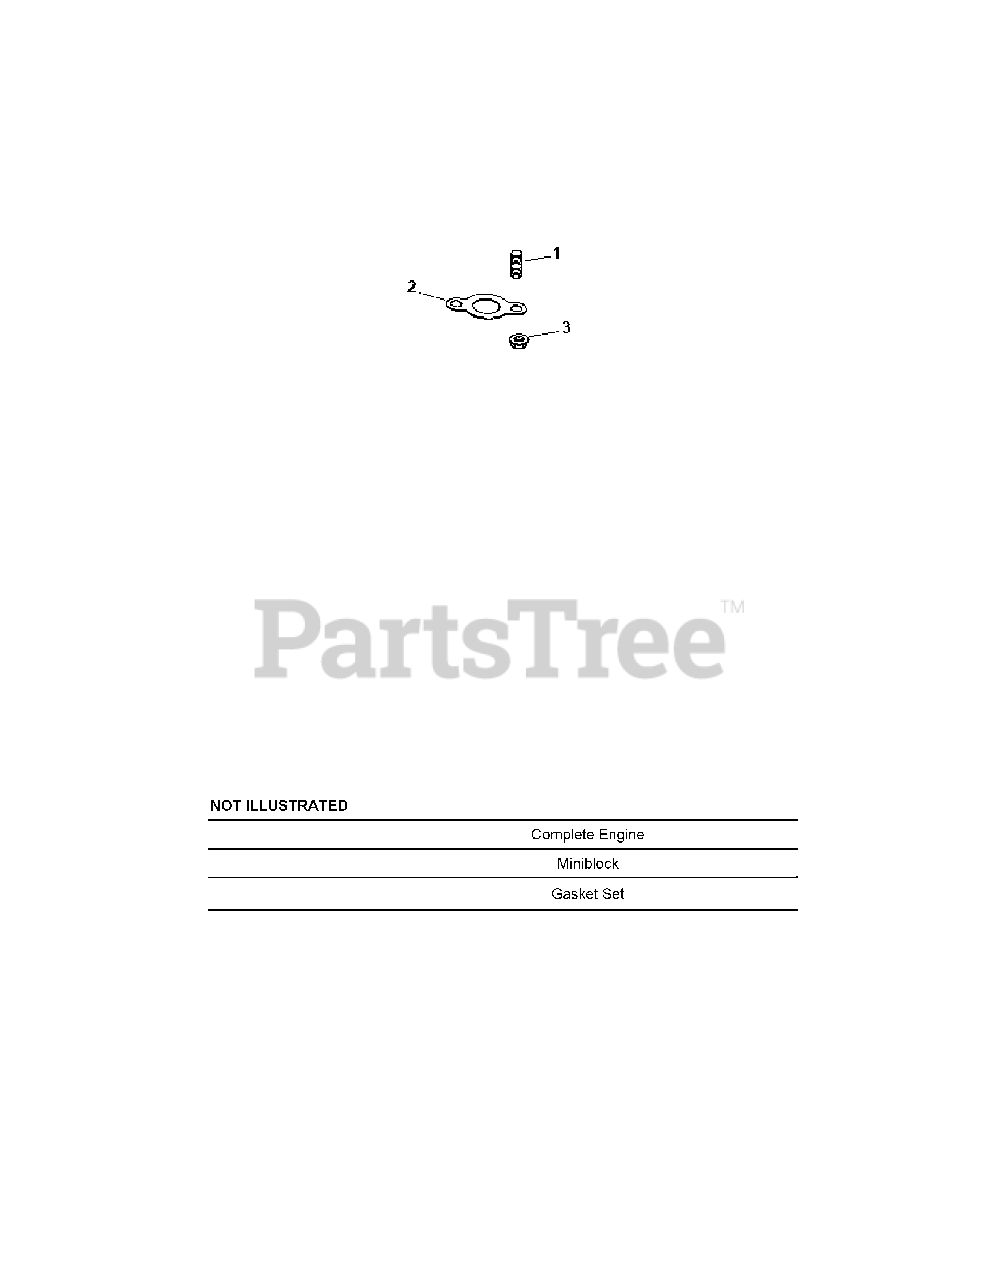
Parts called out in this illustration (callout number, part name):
1	Stud (M8 x 1.25 x 33)
2	Exhaust Gasket
3	Muffler Mounting Nut (M8 x 1.25)
